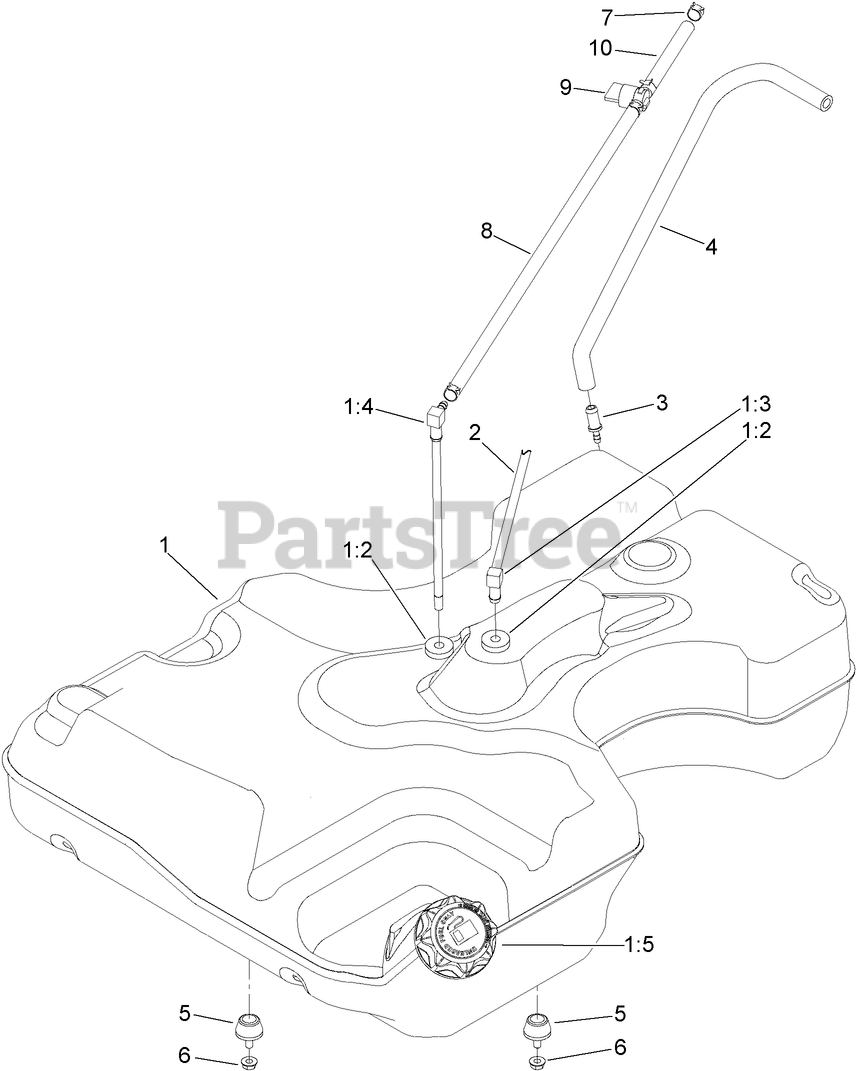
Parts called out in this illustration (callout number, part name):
1	FUEL TANK ASM
1:2	BUSHING
1:3	FITTING-90 ELBOW
1:4	FUEL LINE ASM
1:5	CAP-FUEL, RATCHETING
2	HOSE-FUEL
3	FITTING-STRAIGHT
4	HOSE-FUEL
5	BUMPER-RUBBER
6	NUT-HF
7	CLAMP-HOSE
8	HOSE-FUEL
9	VALVE-FUEL
10	HOSE-FUEL
